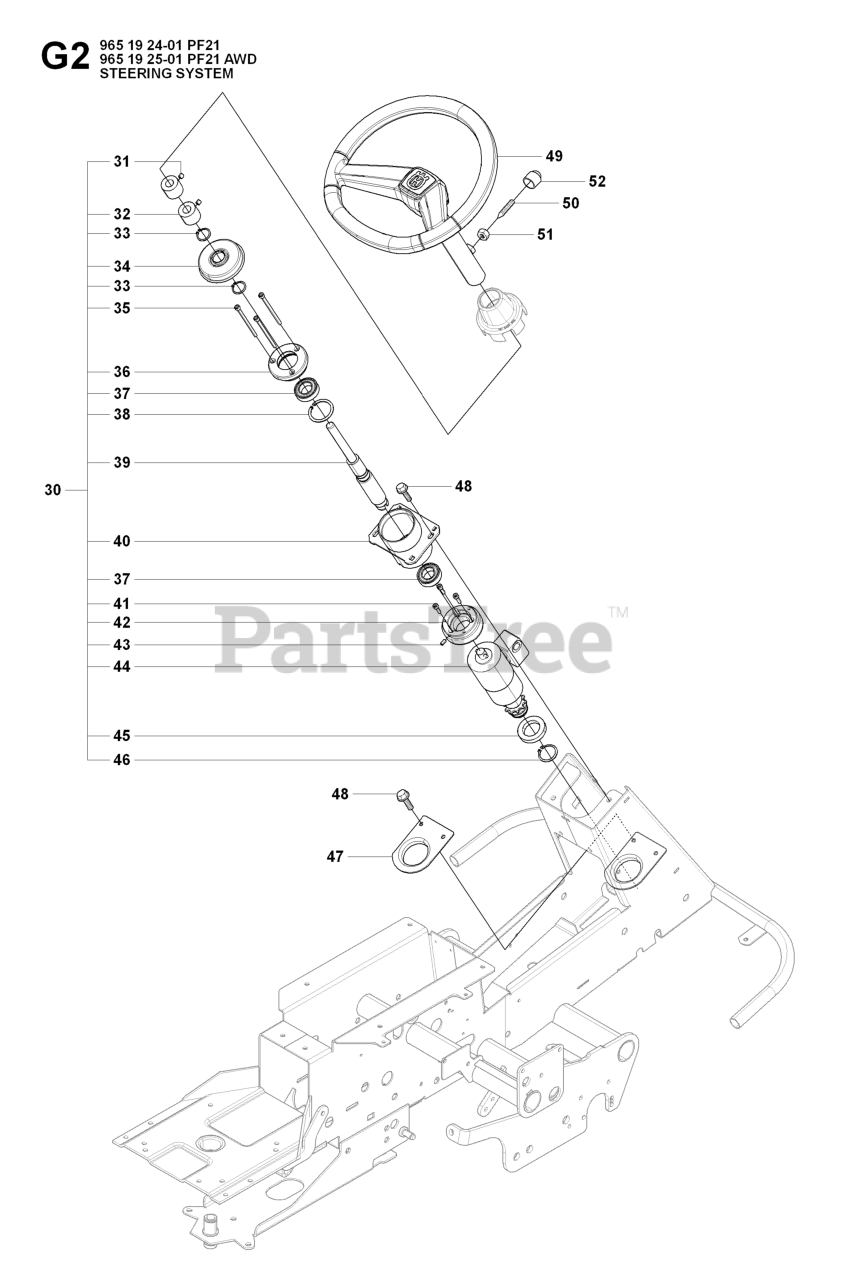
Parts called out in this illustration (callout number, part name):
32	SPACER
33	RETAINING RING SGA 25
35	SCREW IHSCM.
37	Ball Bearing 6005-2rs
38	CIRCLIP SGH 47
41	SCREW MC6S 6X20
43	SPRING PIN
44	COMFORT STEERING
51	NUT
52	PROTECTIVE COVER
